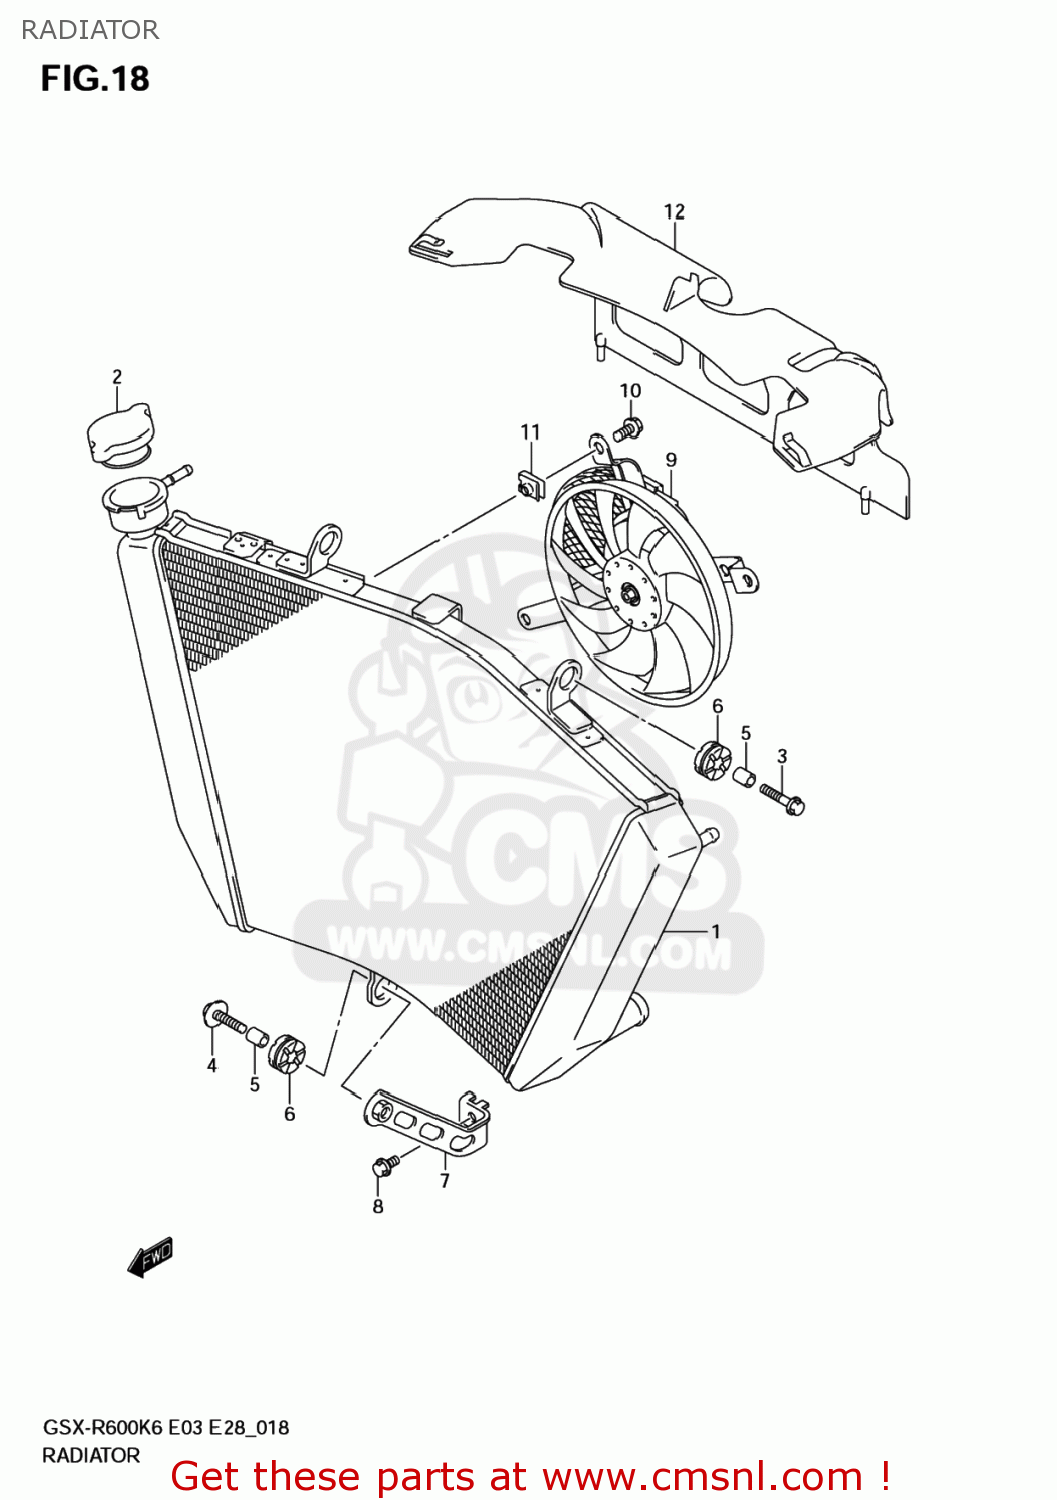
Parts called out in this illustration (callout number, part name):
1	RADIATOR ASSY,WATER
2	CAP,RADIATOR(1.1)
3	BOLT
4	BOLT (6X25)
5	SPACER (6.5X10
6	CUSHION
7	BRACKET,RADIATOR
8	BOLT
9	FAN ASSY,RADIATOR
10	BOLT,FAN ASSY
11	NUT,RADIATOR FAN
12	SHIELD,RADIATOR HEAT
